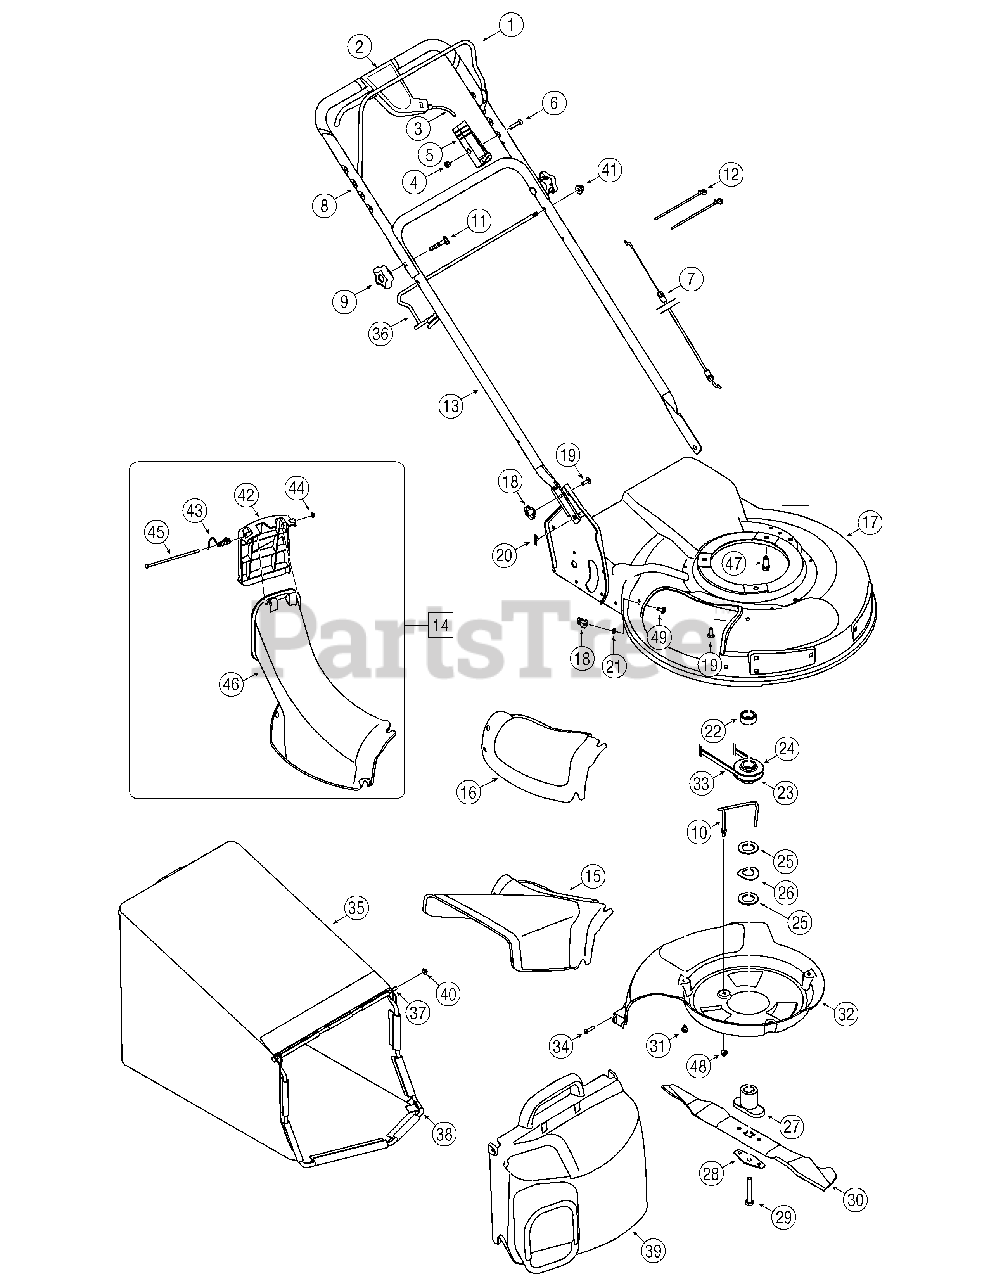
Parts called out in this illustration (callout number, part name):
2	Control Lever Assembly
3	Drive Cable 51"
4	Top Lock Nut 1/4-20
5	Control Housing
6	Oval C-Sunk Screw
7	Control Cable 47"
9	Star Knob
10	Belt Keeper
11	Carriage Bolt 5/16-18 x 2.0
12	Cable Tie
14	Chute Assembly
15	Side-Discharge Chute
16	Mulch Cover
19	Carriage Bolt 1/4-20 x .75"
20	Cotter Pin
21	Push Nut .25 x ID x .50 OD
22	Sleeve Spacer 25mm x 1.375 x .440
23	Half Pulley: Key 25mm x 2.62 OD
24	Half Pulley: Upper 25mm x 2.62
25	Flat Washer 1.00 x 1.75 x .107
26	Spring Washer 1.005 x 1.825 x .048
27	Blade Adapter Kit
28	Blade Bell Support
29	Hex Bolt 3/8-24 x 2.5
30	21" Mulching Blade
31	Screw 1/4-20 x 3.75
32	Baffle
33	Belt 3/8 x 39.24
34	HL Screw #12-16 x 1.00
35	Grass Catcher Assembly
37	Pivot Rod
39	Grass bag Cover
40	Cap Nut
41	Hex Nut 5/16-18
42	Chute Door
43	Torsion Spring
44	Push Cap
45	Pivot Rod
46	Discharge Chute
47	Sems Screw 3/8-16 x 1.00
48	Flange Lock Nut, 14-20
49	Carriage Bolt 1/4-20 x .62
